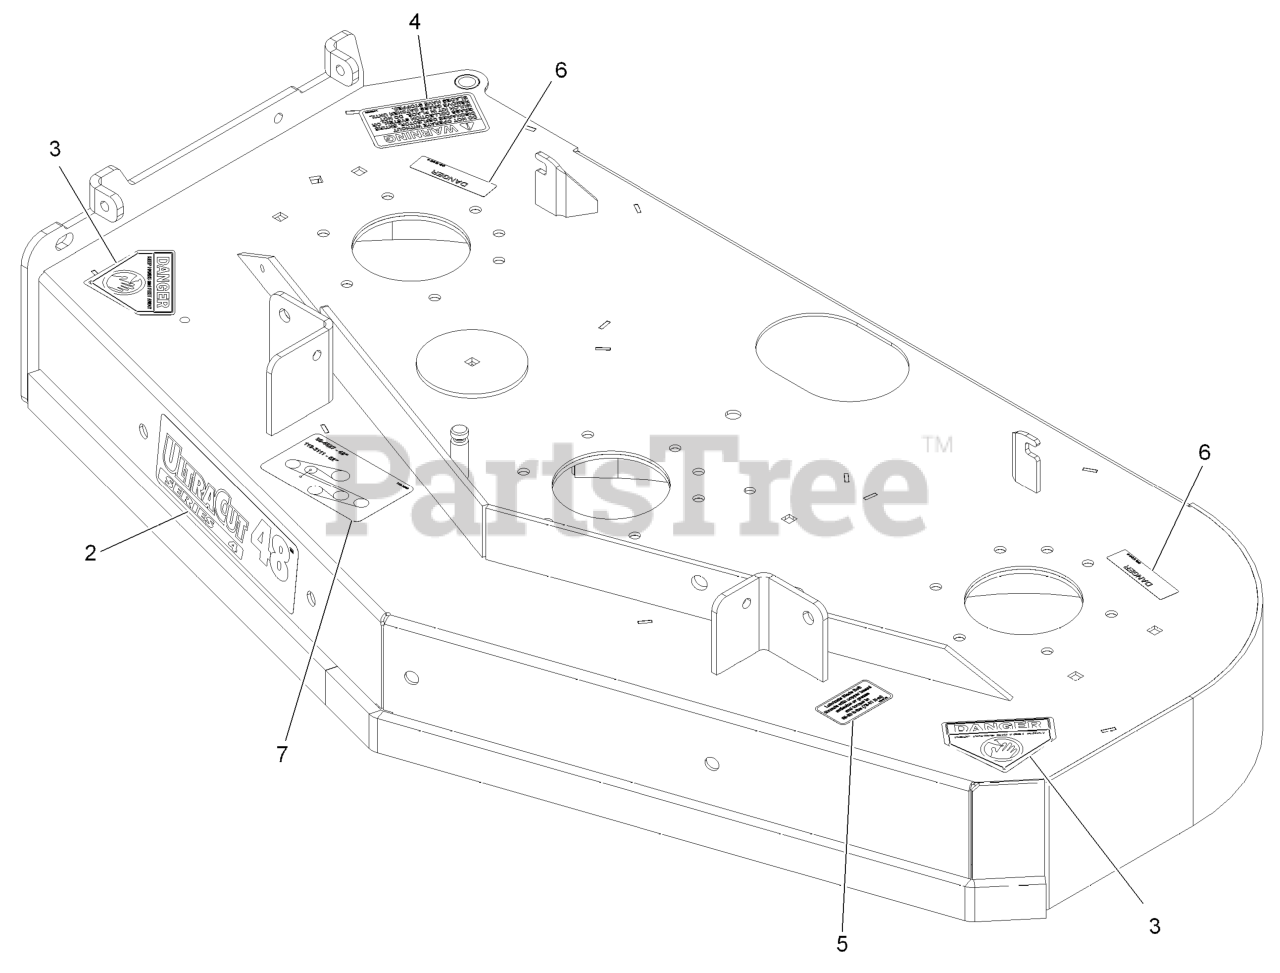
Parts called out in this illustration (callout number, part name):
2	DECAL,ULTRACUT 48 SERIES
3	DECAL-DANGER
4	DECAL-WARNING, DISCHARGE
5	DECAL,BOLT TORQUE
6	DECAL-COVER, MISSING
7	DECAL-BELT ROUTING
